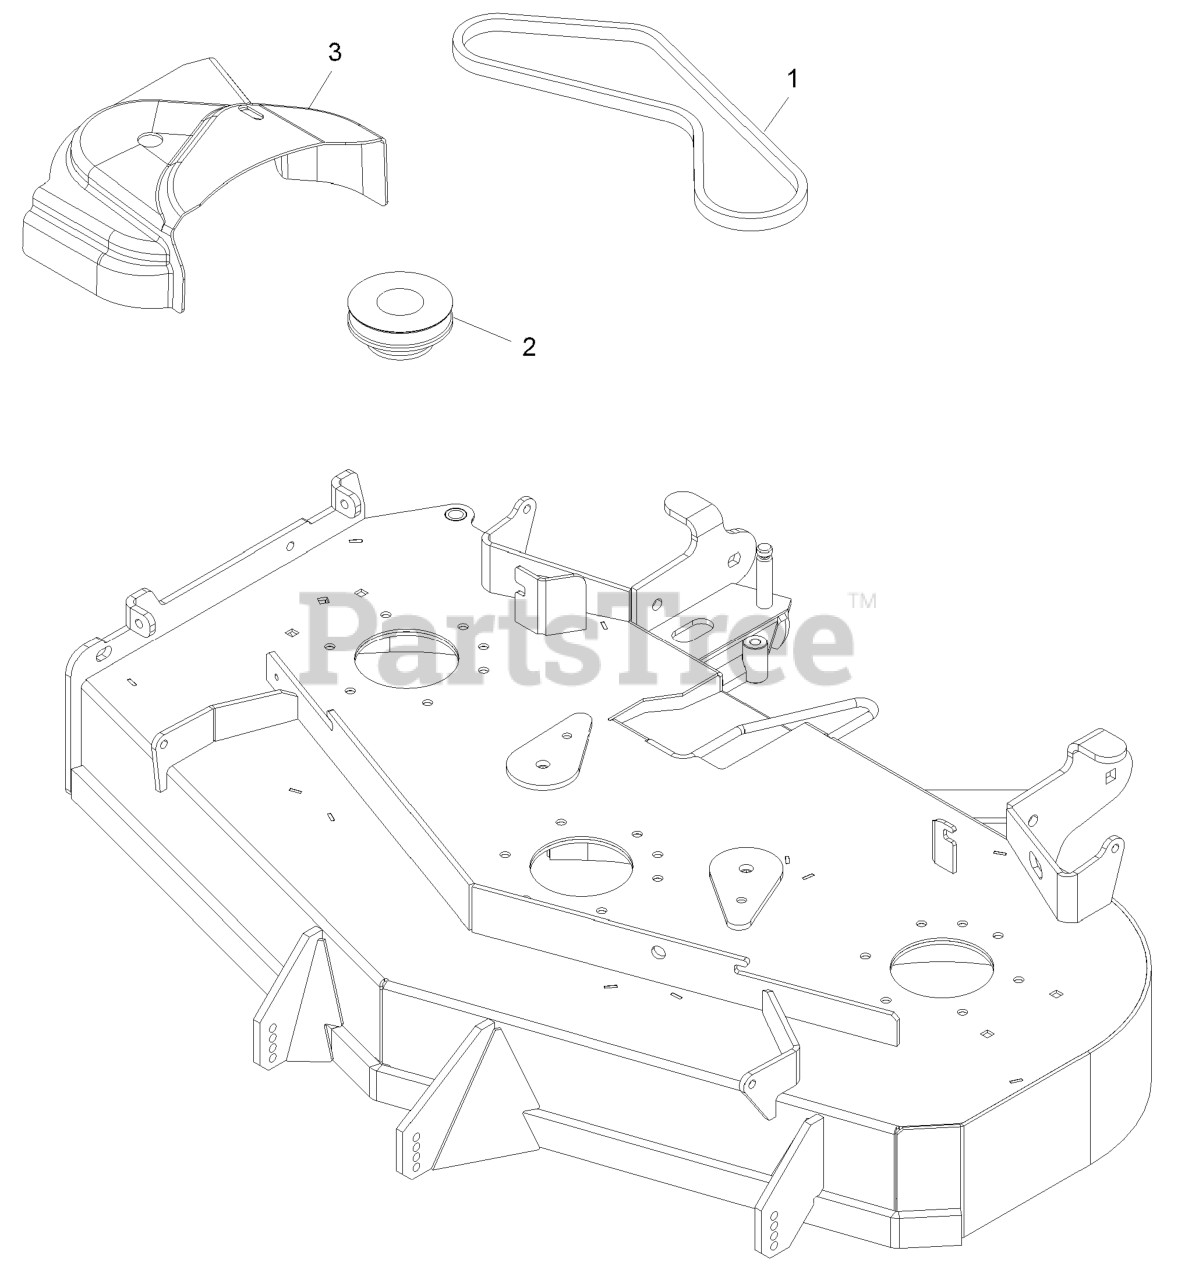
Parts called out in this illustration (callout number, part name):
1	BELT-BLOWER
2	SHEAVE,DRIVE LZUV 486
3	COVER,BELT UV 48
